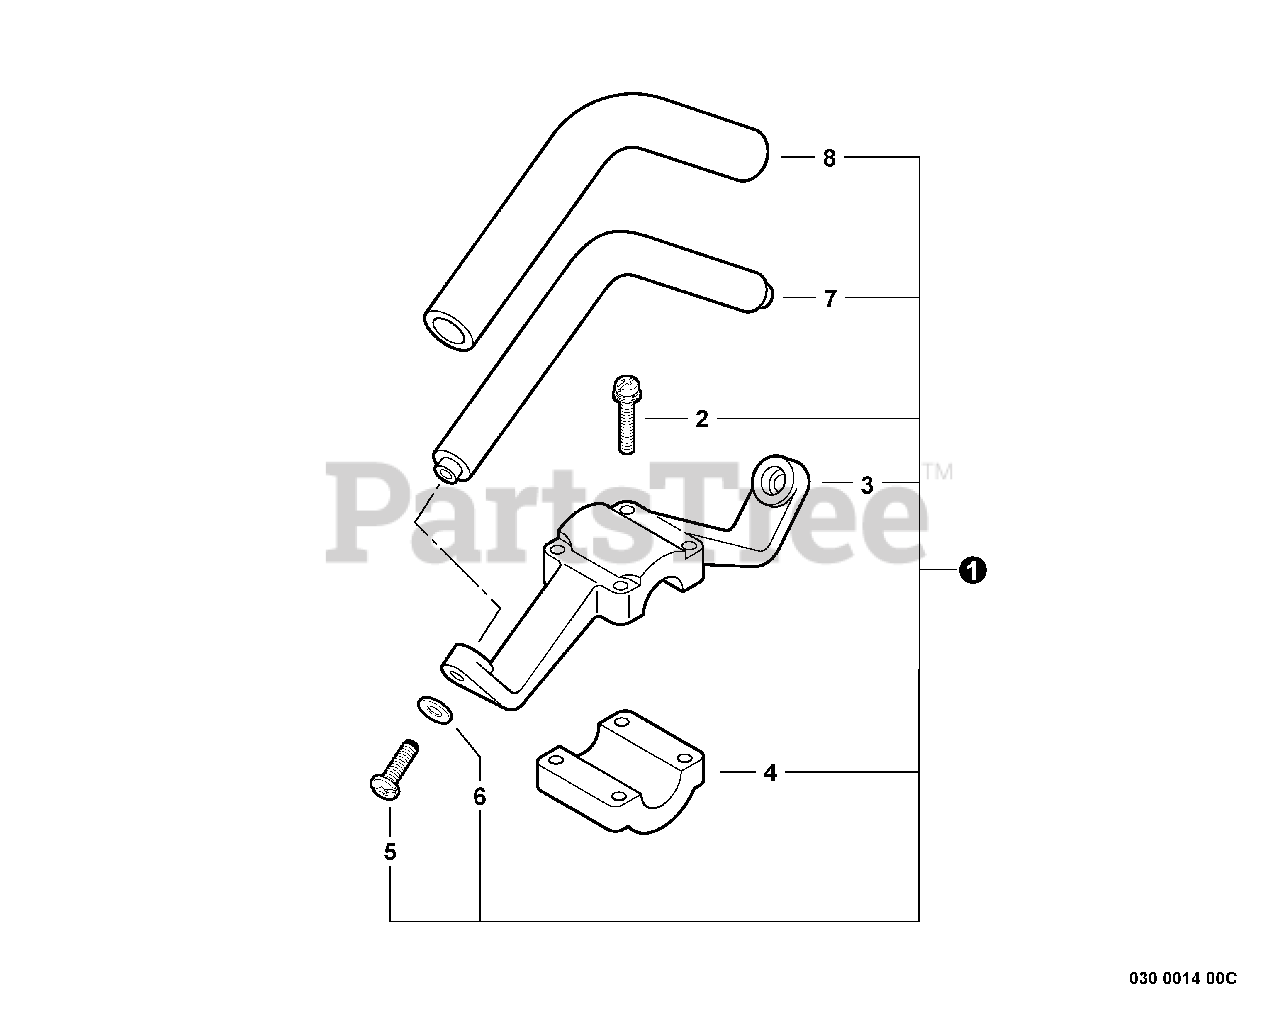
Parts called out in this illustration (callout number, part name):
1	HANDLE ASSY - FRONT
2	SCREW - 5X35
3	BRACKET, HANDLE - UPPER
4	BRACKET, HANDLE - LOWER
5	SCREW - 5X20 -- TAPPING
6	WASHER - 5
7	HANDLE - FRONT
8	GRIP, HANDLE
